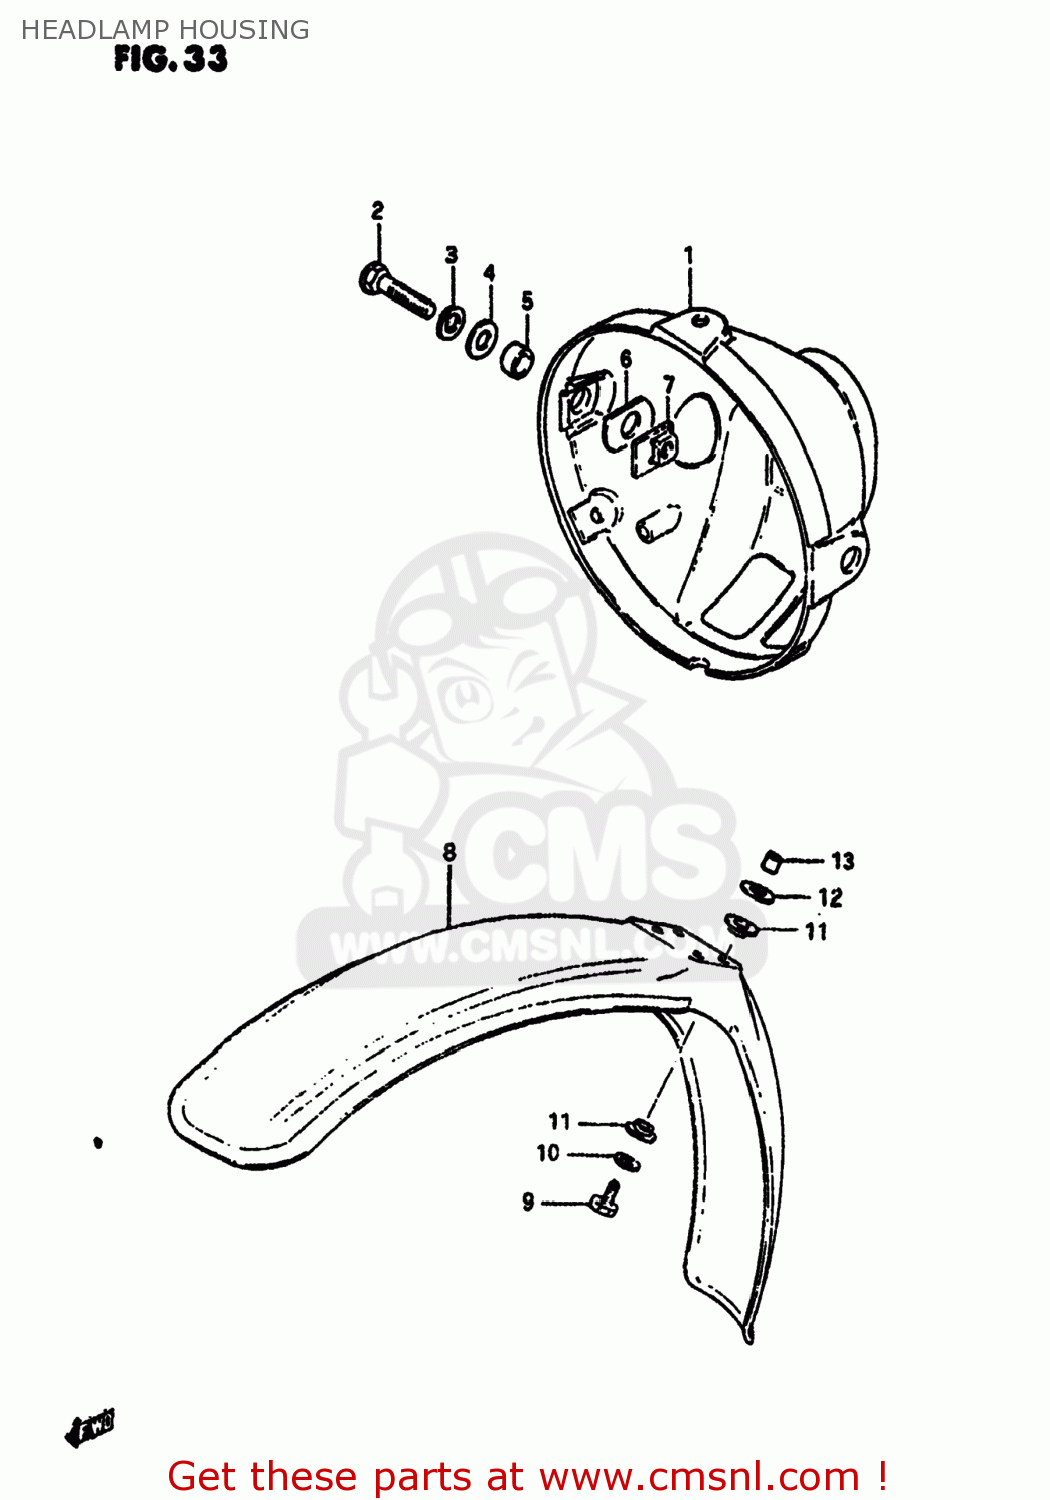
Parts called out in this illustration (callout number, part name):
1	HOUSING,HEADLAMP
2	BOLT
3	LOCK WASHER
4	WASHER
5	SPACER (8.8X12X7)
6	CUSHION
7	PLATE,HEADLAMP HOUSING
8	FENDER,FRONT
9	BOLT
10	LOCK WASHER
11	SPACER
12	WASHER (6.5X13X2.3)
13	SPACER (6.8X10X10)
